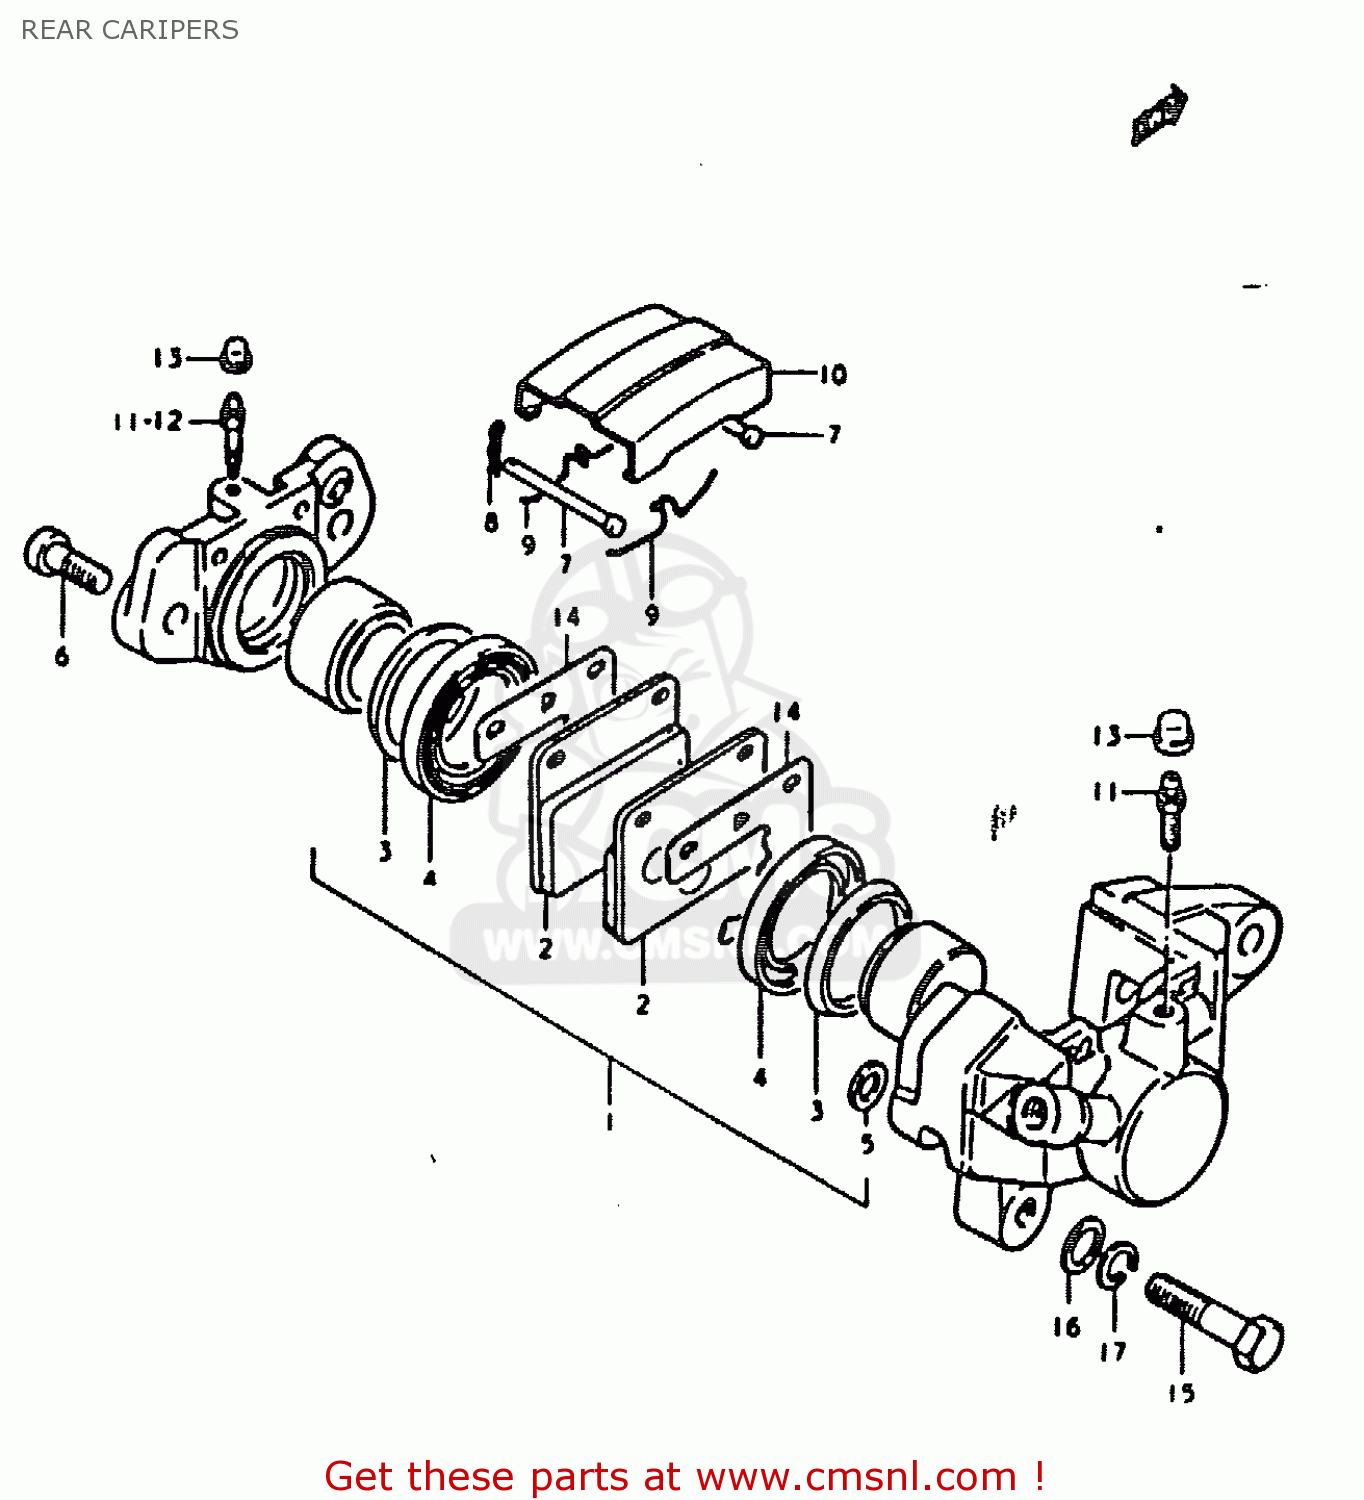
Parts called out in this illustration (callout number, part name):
1	PISTON SET
2	PAD,BRAKE
3	SEAL,PISTON
4	BOOT,PISTON
5	SEAL,PISTON
6	BOLT,HOUSING
7	PIN,PAD
8	CLIP,PAD PIN
9	SPRING
10	COVER,DUST
11	BLEEDER
13	CAP,BREATHER
14	SHIM,RR CALIPER
15	BOLT 10X34
16	WASHER
17	LOCK WASHER
